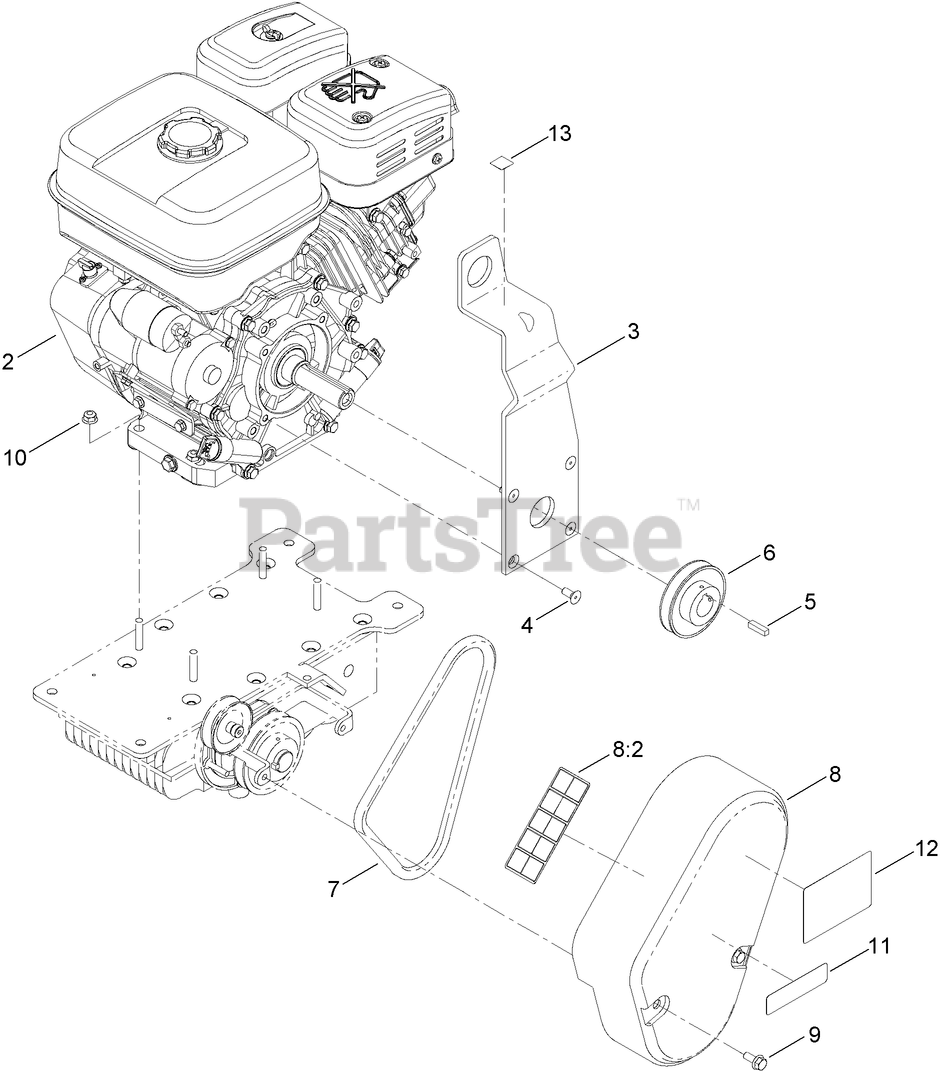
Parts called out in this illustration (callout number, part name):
2	ENGINE-HONDA, GX240
3	EYE-LIFT
4	SCREW
5	KEY-SQUARE
6	SHEAVE
7	BELT-V
8	BELT GUARD ASM
8:2	DECAL-WARNING, POWER TROWEL
9	SCREW-HHF
10	NUT-HF, NI
13	DECAL-POINT, LIFT
